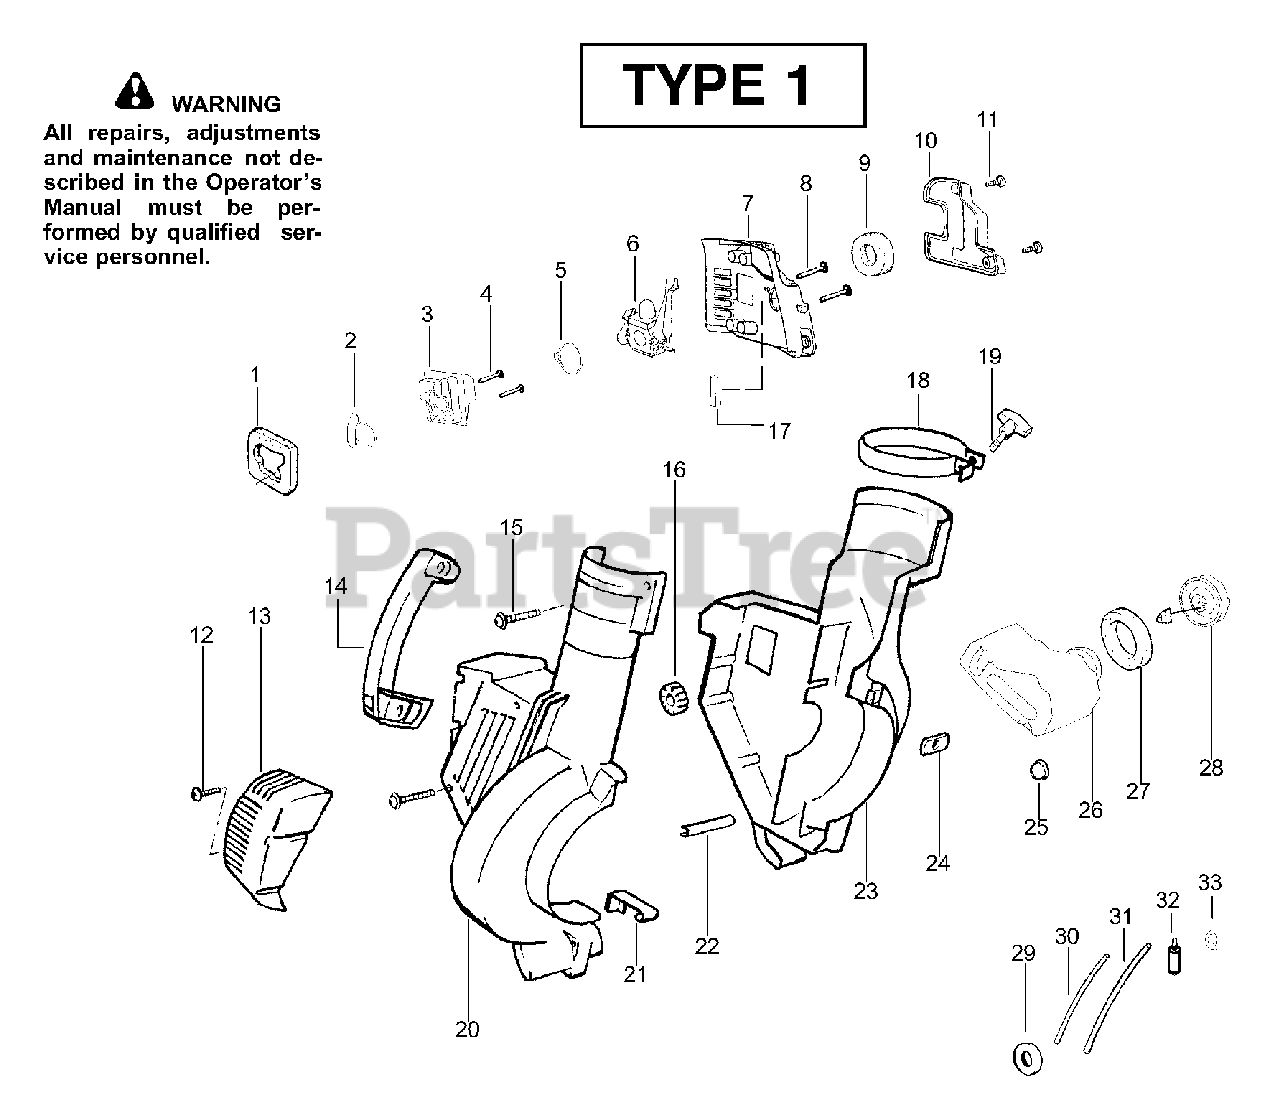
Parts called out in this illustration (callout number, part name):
1	Air Dam (kit)
2	Gasket-Adapter (kit)
3	Carburetor Adaptor
5	Gasket-Carburetor (kit)
6	Kit-Carb Ass'y (C1Q-W11)
8	Screw-Carb.
9	Filter-Air
10	Cover-Air Filter
11	Screw-Air Box Cover
13	Assy-Muffler Cover
16	Isolator
17	Foam 25.4mm (kit)
18	Clamp-Blower Tube
19	Knob-Tube Clamp
20	Housing-Right
21	Spring-Cover Latch
22	Guide-Starter Rope
23	Housing-Left
25	Isolator-Crankcase
26	Assy-Fuel Tank
27	Gasket-Fuel Tank (kit)
28	Fuel Cap w/Retainer
29	Grommet-Shroud
30	Kit-Line Carb/Purge
31	Kit-Line Tank/Purge
32	Assy-Fuel Pick-up
33	Grommet-Fuel line (kit)
